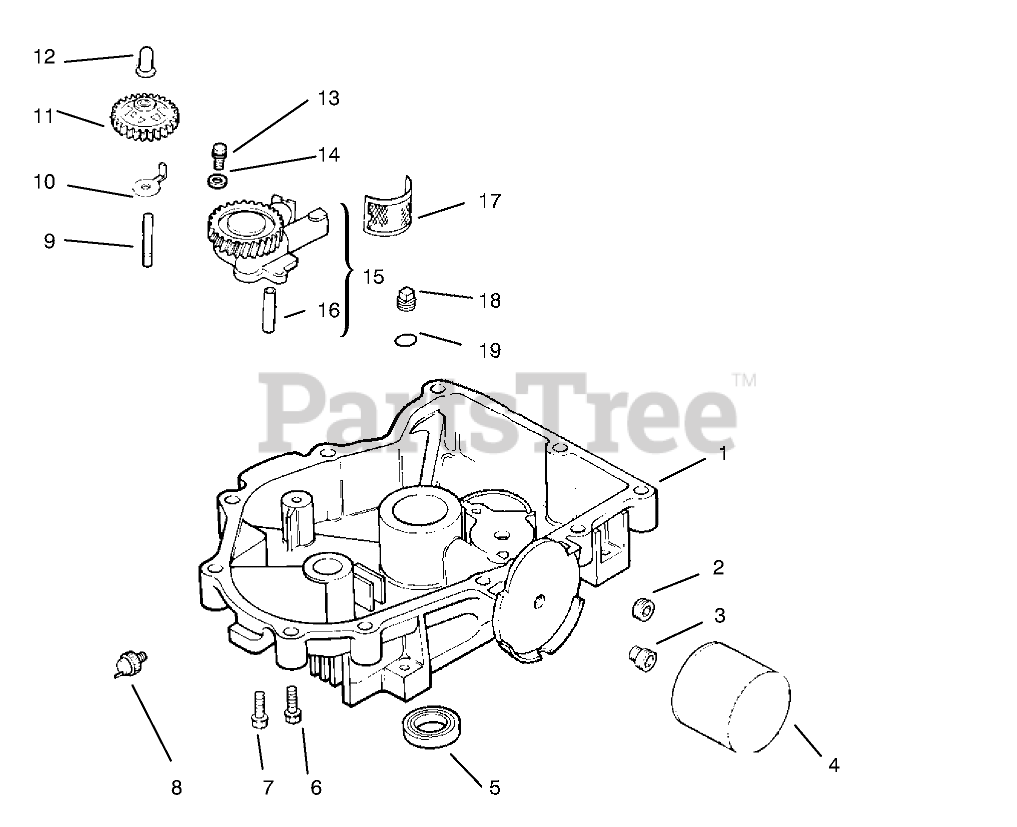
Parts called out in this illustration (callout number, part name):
1	Oil Pan
2	Plug-Hex
3	Nipple-Filter, Oil
4	Filter-Oil
5	Seal-Oil
6	Screw
7	Screw
8	Switch, pressure
9	Shaft-Gear, Governor
10	Tab-Locking
11	Governor Gear ASM
12	Pin-Governor
13	Screw
14	Washer
15	Oil Pump ASM INC 16
16	Tube-Oil Pickup
17	Screen-Oil Pickup
18	Plug
19	O Ring
